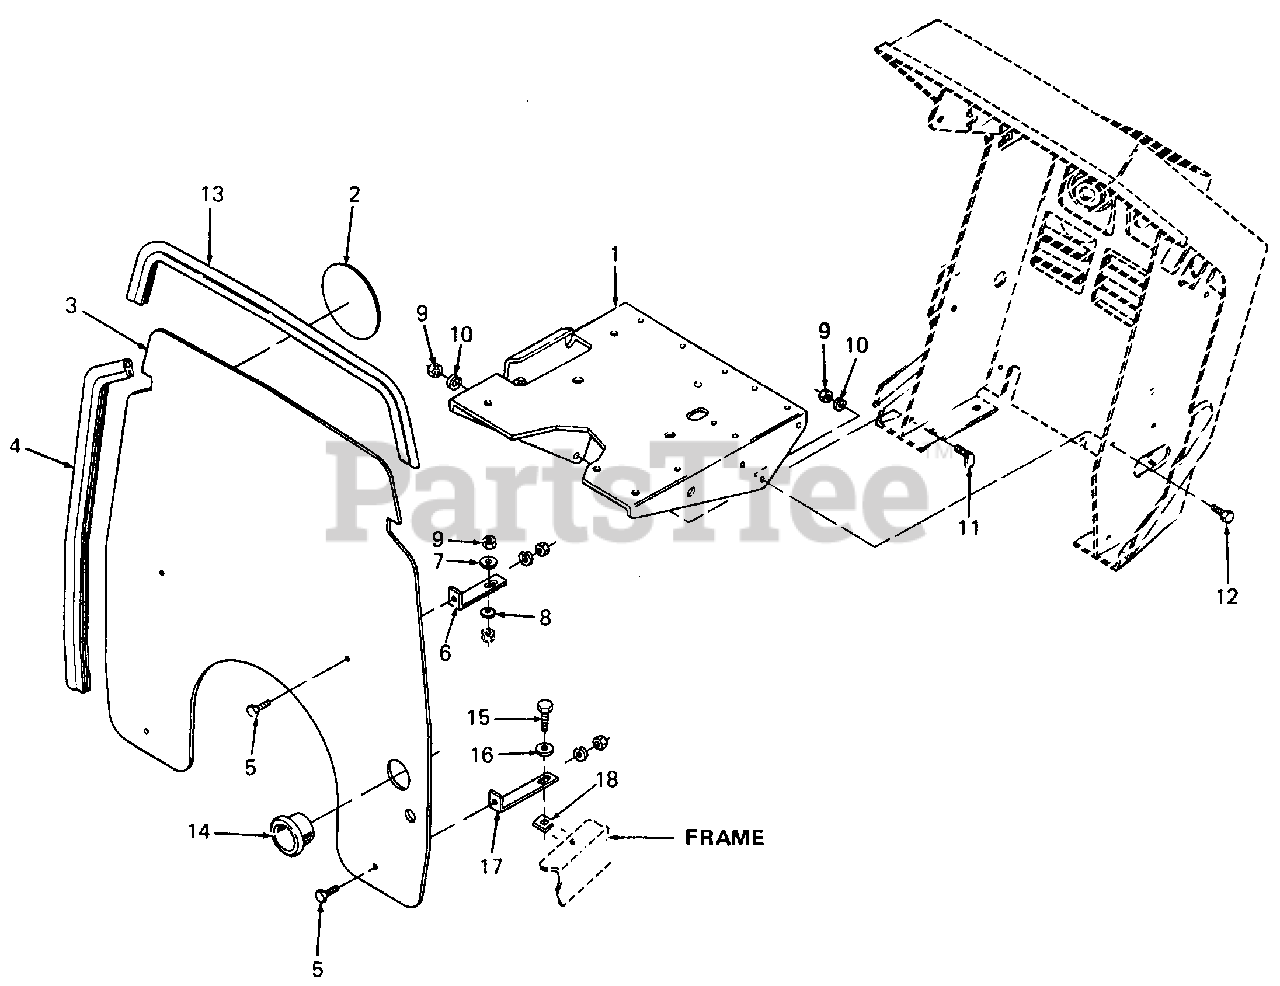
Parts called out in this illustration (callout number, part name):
1	Tray Assy, Battery
2	Disc, Silicone Rubber
3	Baffle, Heat
4	Seal, Heat Baffle, 19.0" Lg
5	Screw, Hex Cap, 1/4-20 X .50 Lg GR5
6	L-Bracket, 1.1 Lg
7	Washer, Bell, .265 X .75 X .062 Thk
8	Washer, Flat, .281 X .50 X .063 Thk
9	Nut, Hex, 1/4-20 GR5
10	Washer, Lock, 1/4
11	Bolt, J-Type, 1/4-20
12	Screw, Hex Cap, 1/4-20 X .62 Lg GR5
13	Seal, Heat Baffle, 17.0" Lg
14	Bushing, Snap
15	Screw, Hex Cap, 5/16-18 X .50 Lg
16	Washer, Bell, .345 X .88 X .060 Thk
17	L-Bracket, 1.9 Lg
18	Nut, U-Type, 5/16-18
